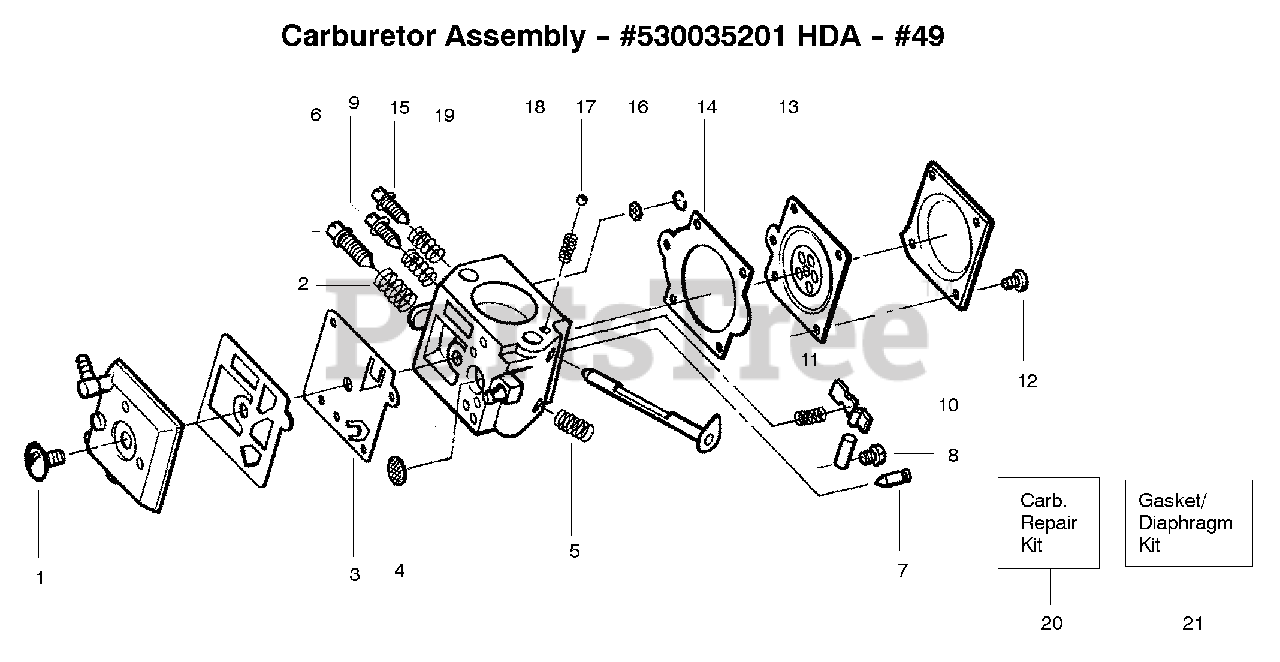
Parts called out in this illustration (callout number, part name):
2	Idle Adjust Spring
3	Fuel Pump
4	Inlet Screen
5	Throttle Spring
6	Idle Adjust Screw
7	Inlet Needle Valve
9	Idle Needle
10	Metering Lever
13	Metering Diaphragm Ass'y.
14	Metering Diaphragm Gasket
15	High Speed Needle
16	Check Valve Screen
18	Spring--Choke
19	Needle Adjusting Spring
20	Carb. Repair Kit
21	Gasket/Diaphragm Kit
530035201	Carburetor Assembly HDA-#49
